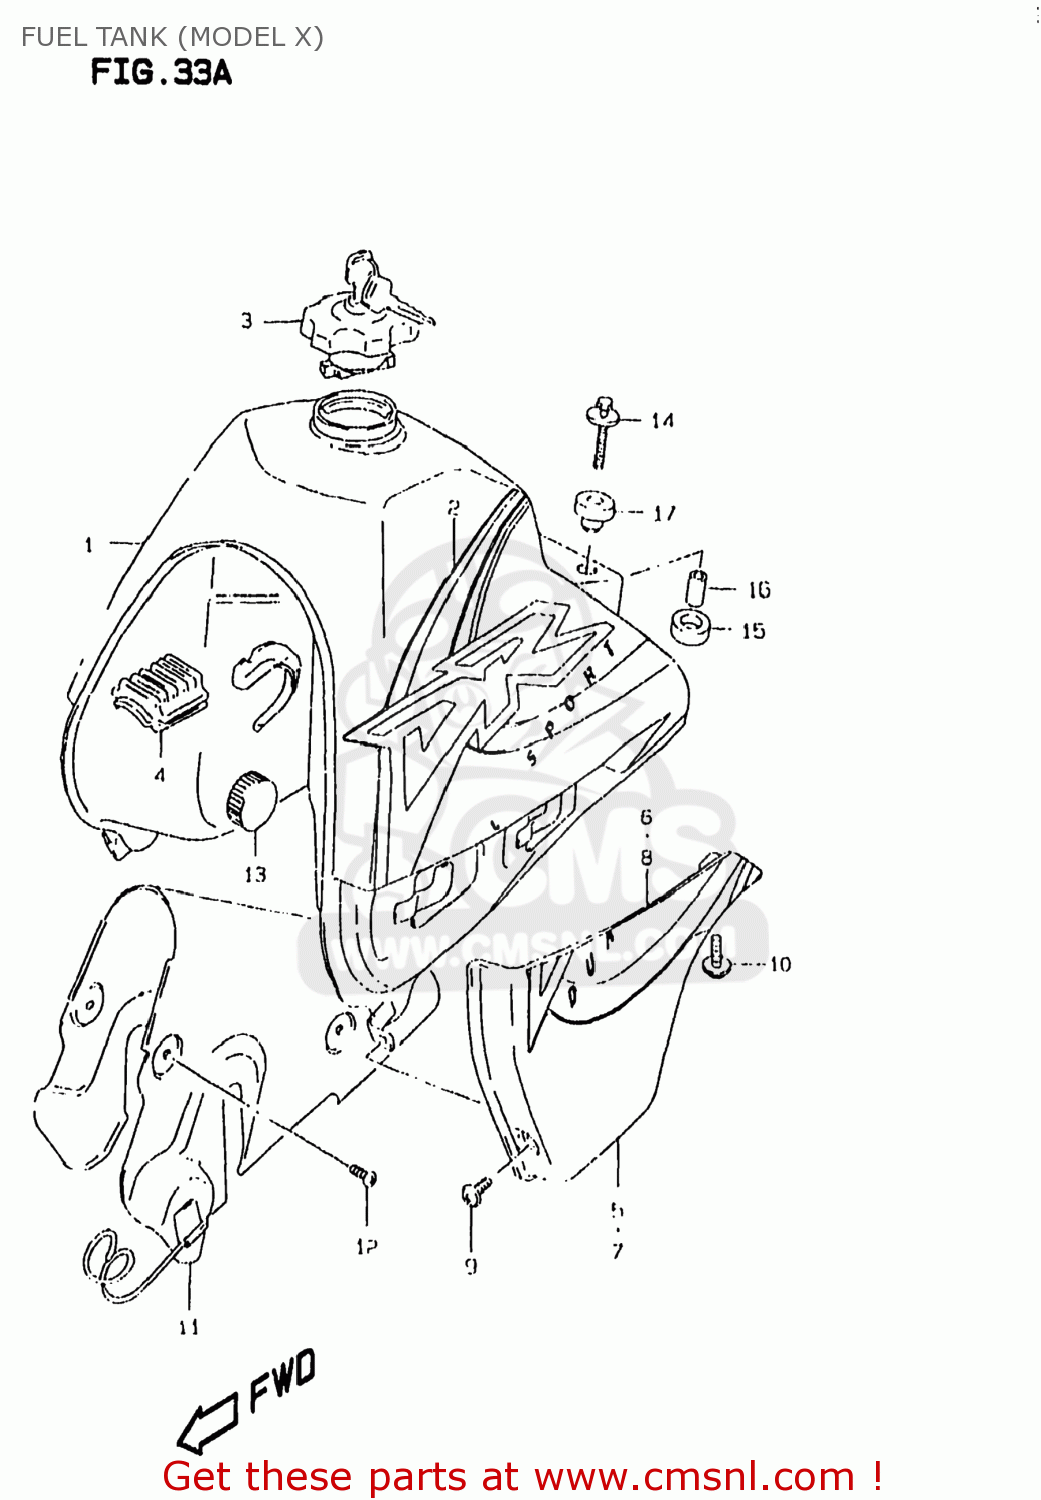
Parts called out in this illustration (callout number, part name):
1	TANK ASSEMBLY,FUEL
2	TAPE SET,FUEL TANK
3	CAP SET,FUEL TANK
4	CUSHION,FUEL TANK FR UPR
5	COVER,FUEL TANK,R
6	TAPE,FUEL TANK COVER,RIGHT
7	COVER,FUEL TANK,L
8	TAPE,FUEL TANK COVER,LEFT
9	SCREW
10	SCREW(6X12)
11	SHIELD,FUEL TANK
12	BOLT
13	CUSHION
14	BOLT(6X30)
15	CUSHION
16	SPACER(6.5X9X18)
17	CUSHION
